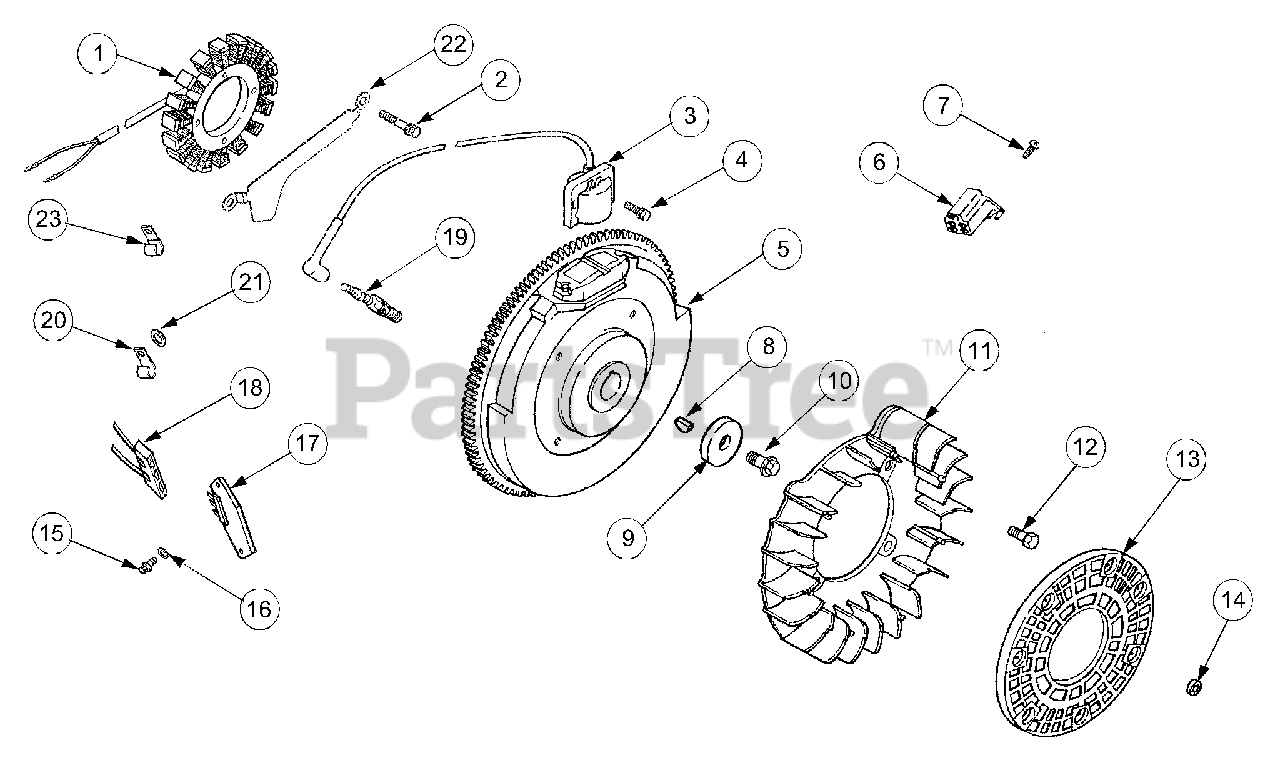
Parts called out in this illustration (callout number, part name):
1	Stator Kit, 15 Amp
2	Screw, Stator Mtg. M5 x .8 x 25
3	Module, Ignition
4	Screw, Module M5 x .8 x 20
5	Flywheel Assembly
7	Screw, Hex Sems #10-16 x 1/2
9	Washer, Flywheel Mtg. Screw
10	Screw, Flywheel Mtg, M10x1.5 x 46
11	Fan
12	Bolt, Shoulder
13	Screen, Grass
14	Retainer
15	Screw Phillips Hd., #11-16 x .875
16	Washer, Plain
17	Regulator - Rectifier
18	Connector, Regulator-Rectifier
19	Spark Plug
20	Clip, Cable
21	Washer, Plain 1/4"
22	Bracket, Stator Wire
